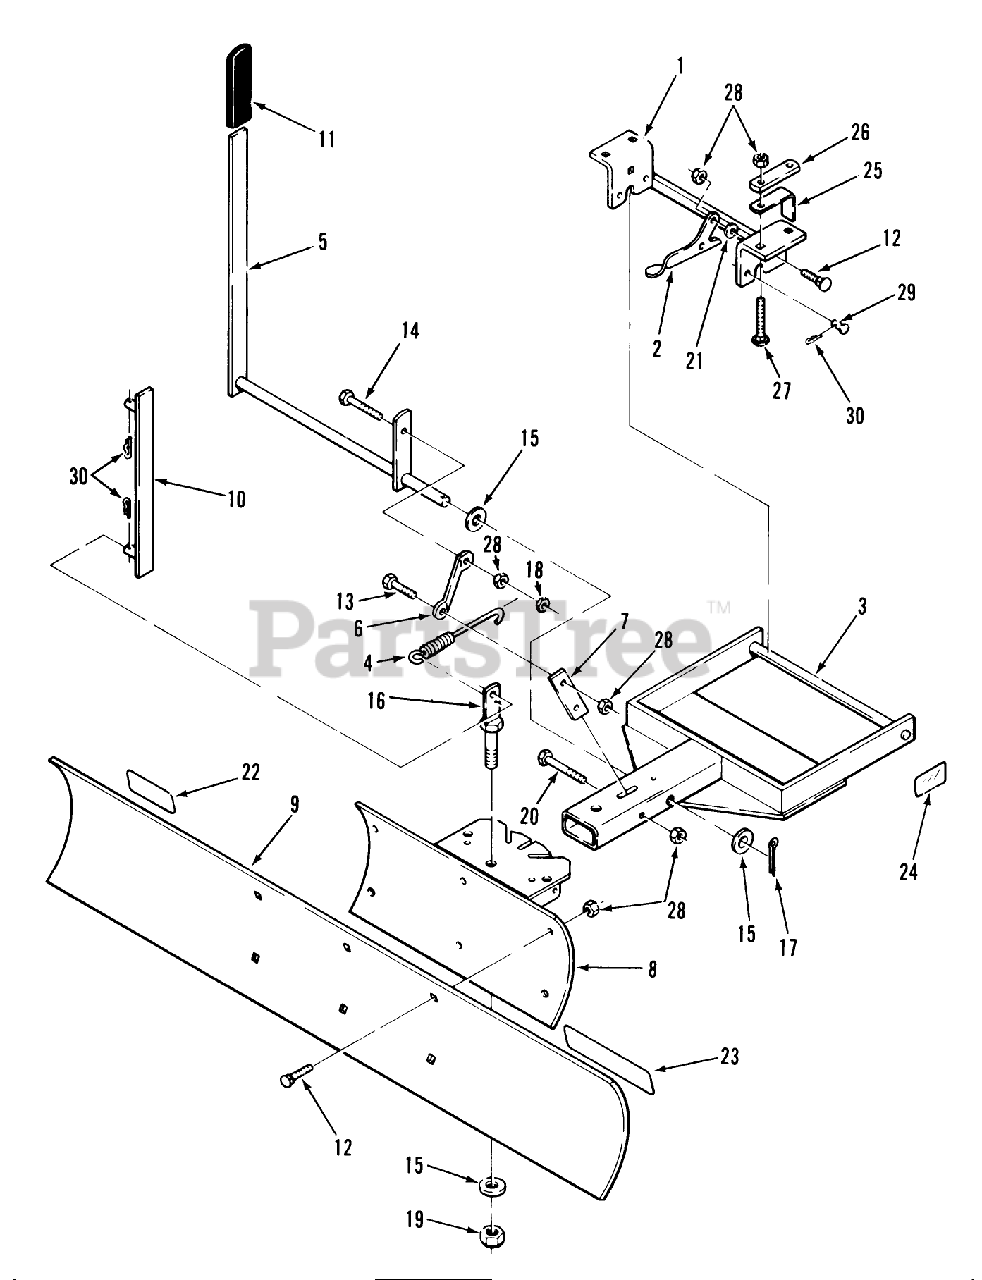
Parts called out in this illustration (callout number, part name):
1	Bracket
2	PLATE-LATCHING
3	ASS'Y-FRAME R
4	SPRING
5	ASS'Y-LATCH HANDL R
6	Latch Link
7	Latch
8	ASS'Y-QUADRANT
9	Blade
10	Lift Link
11	GRIP
12	Bolt
13	BOLT
14	Bolt
15	Washer
16	Wa-Scrw
17	Cotter Pin
18	NUT-HEX, JAM
19	Nut
20	HHCS
21	Washer
22	DECAL-DANGER
23	Decal
24	DECAL-OVERLAY
25	SPACER-BRACKET
26	BRACKET-REAR LINK MOUNTING
27	Bolt-Carriage
28	NUT
29	Pin
30	Hairpin
